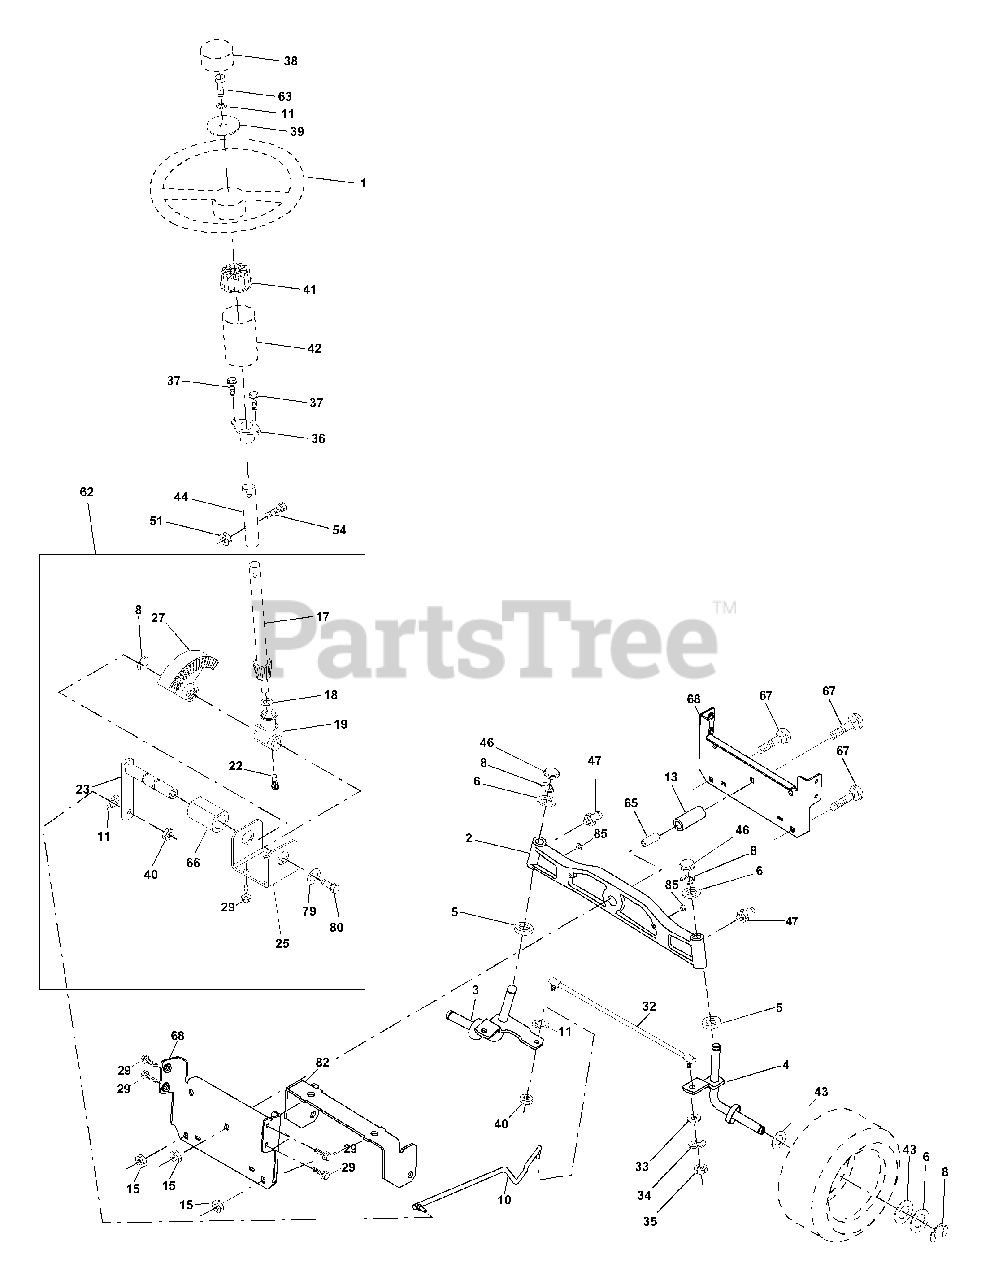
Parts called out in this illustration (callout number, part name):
1	Wheel Steering
2	Axle Asm Cast Iron LT
3	Spindle Asm LH
4	Spindle Asm RH
5	Bearing Race Thrust Harden
6	Washer 25/32 X 1-5/8 X 16 Ga
8	Ring Klip #t5304-75
10	Link Drag
11	Washer Lock Hvy Hlcl Spr 3/8
13	Spacer Brg Axle Front
15	Nut Hex Flange Lock
17	Shaft Asm Strg
18	Washer Thrust 515x 750x 033
19	Support Shaft
22	Screw Hex Wsh Hd Torx
23	Shaft Asm Pittman
25	Bracket Steering
27	Gear Sector
29	Screw 3/8-16 x .75
32	Rod Tie
33	Washer 11/32 x 3/4 x 16 Ga
34	Washer Lock Hvy Hlcl Spr 5/16
35	Crownlock Nut 5/16-24 Unf
36	Bushing Strg
37	Screw
38	Insert Cap Strg Wh
39	Washer 13/32 X 1-1/2 X 11 Ga
40	Lock nut
41	Adaptor Wheel Strg
42	Boot Steering Dash
43	Washer 25/32 X 1 1/4 X 16 Ga
44	Extension Steering Shaft LR/LT
46	Cap Spindle Fr Top Blk
47	Fitting Grease
51	Nut Lock Hex w/Ins 5/16-18
54	Bolt Fin Hex 5/16-18 Unc x 1-1/4
62	Kit, Steering Assembly Svc
63	Bolt Fin Hex 3/8-16unc x 1 Gr. 5
65	Spacer Brace Axle
66	Bearing Arm Pittman
67	Bolt Rdhd Sq 3/8-16 Unc x 2-3/4
68	Axle, Brace
79	Washer 13/32 x 1-1/4 x 12 Ga.
80	Bolt Hex Nylon 3/8-16 x 3/4
82	Bracket Susp Chassis Front
85	Fastner Christmas Tree
